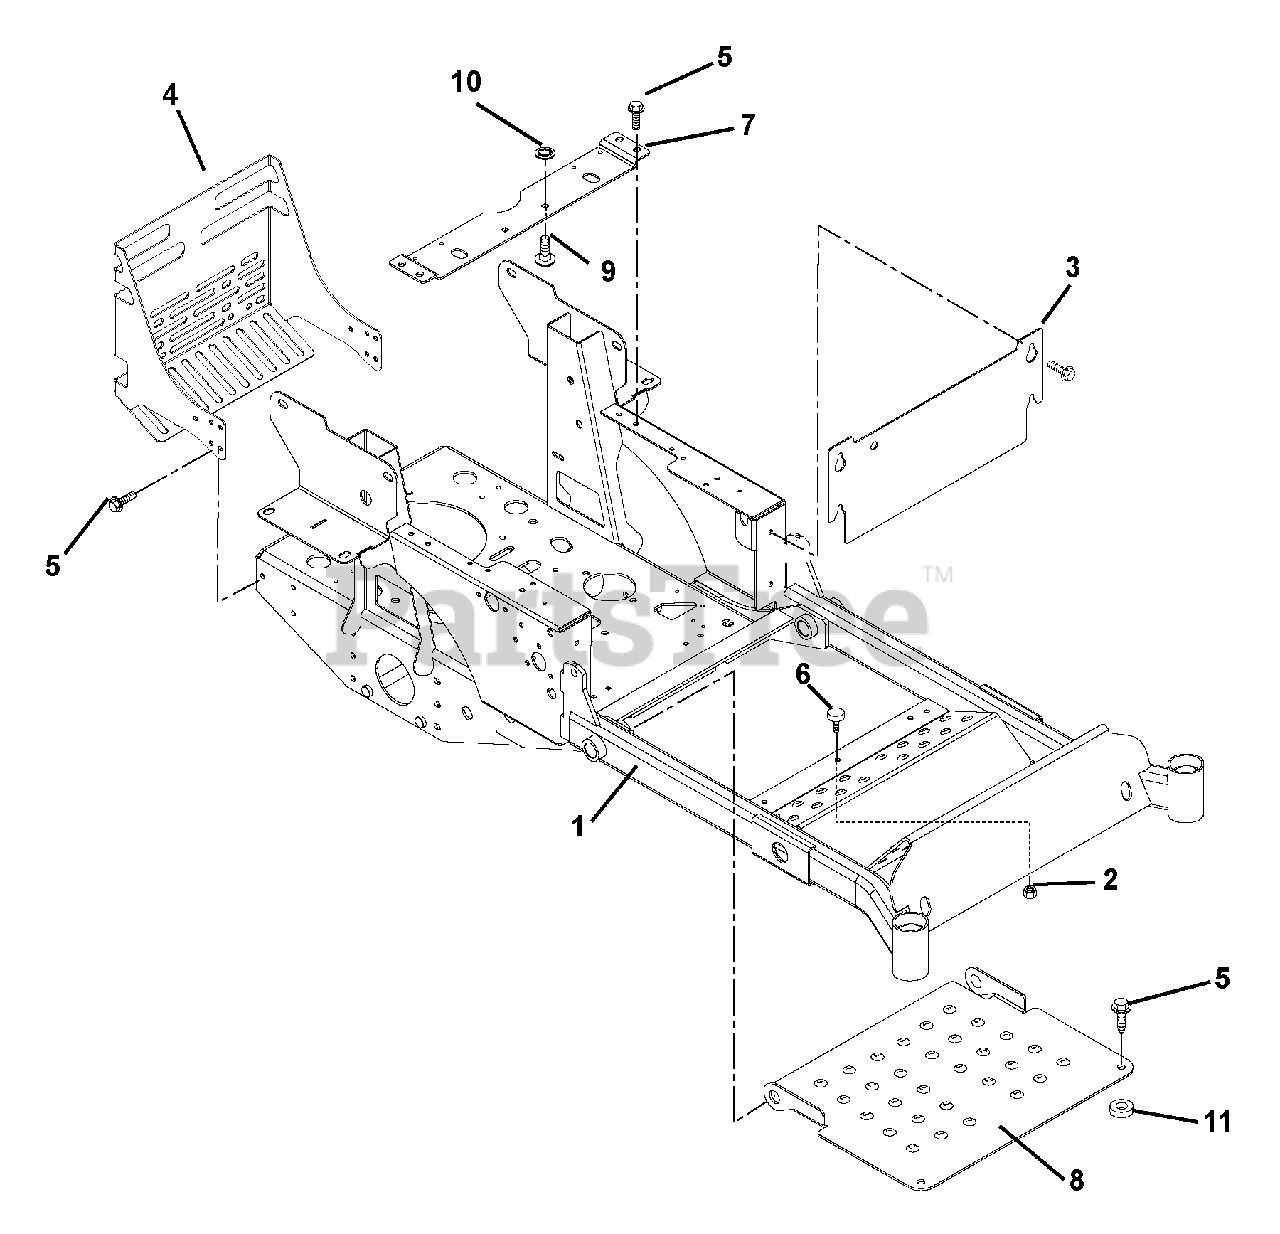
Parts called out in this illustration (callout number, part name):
1	WMT, FRAME COMPACT-Z
2	@NUT-SPNLK-FLG .312-18 YWZC
3	PANEL, ACCESS
4	WMT, BUMPER CZ W/ HEAT SHIELD
5	@SCR-TAP .38-16X.75 HWH TR YWZ
6	BUMPER, RUBBER
7	SUPPORT, SEAT
8	PANEL, INSPECTION
9	@BLT-RHDSSQNK .31-18X.75 G5YZ
10	NUT-PUSH .312
11	SPACER .380X.750X.236
